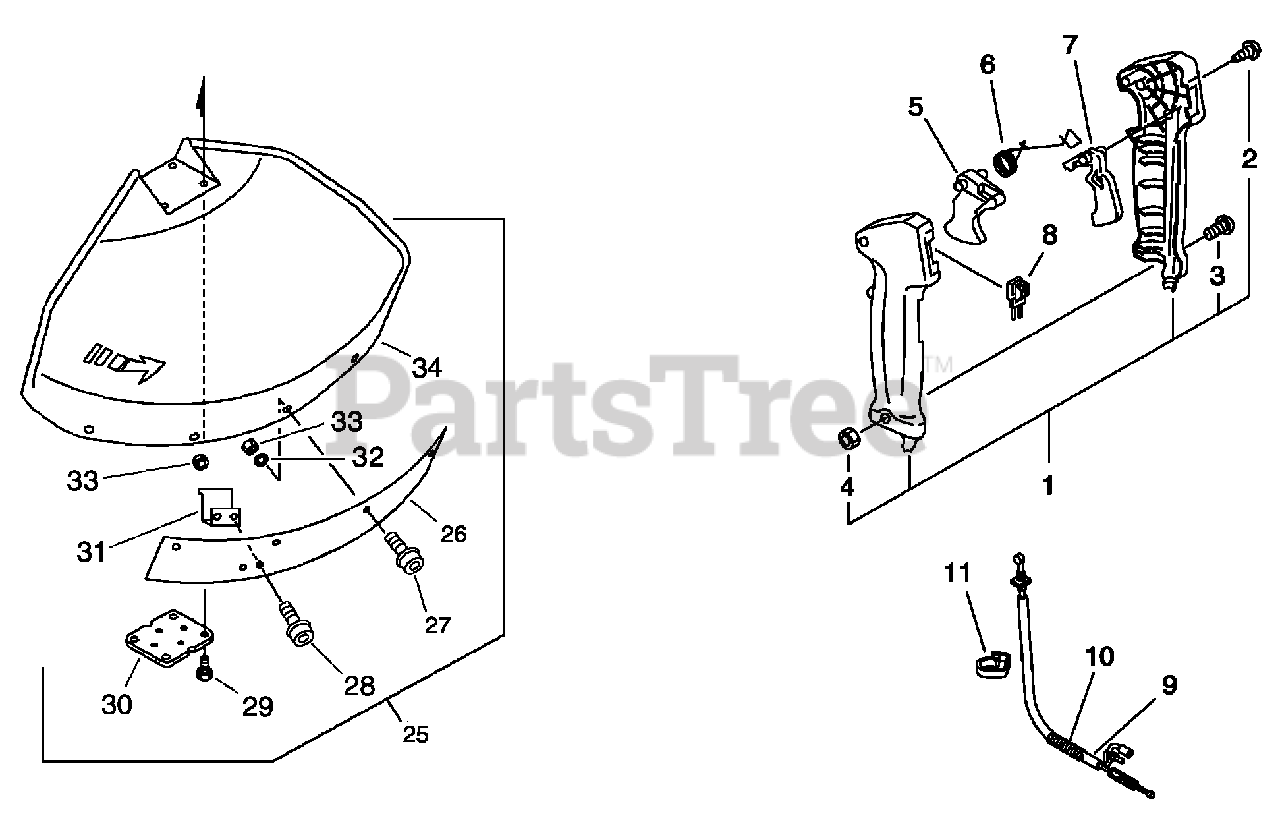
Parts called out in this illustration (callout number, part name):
1	THROTTLE CONTROL ASSY
2	SCREW - 3X25
3	SCREW - 5X30
5	TRIGGER, THROTTLE
6	SPRING, LOCKOUT LEVER
7	LOCKOUT, THROTTLE
8	IGNITION SWITCH ASSY
9	CABLE, THROTTLE
10	TUBE, PROTECTIVE - CORRUGATED
25	DEBRIS SHIELD ASSY
26	GUARD, SHIELD
27	SCREW - 5X18
28	SCREW - 5X14
29	BOLT - 5X25
30	BRACKET, SHIELD
31	KNIFE, TRIMMER LINE
32	WASHER - 5
34	SHIELD, DEBRIS
